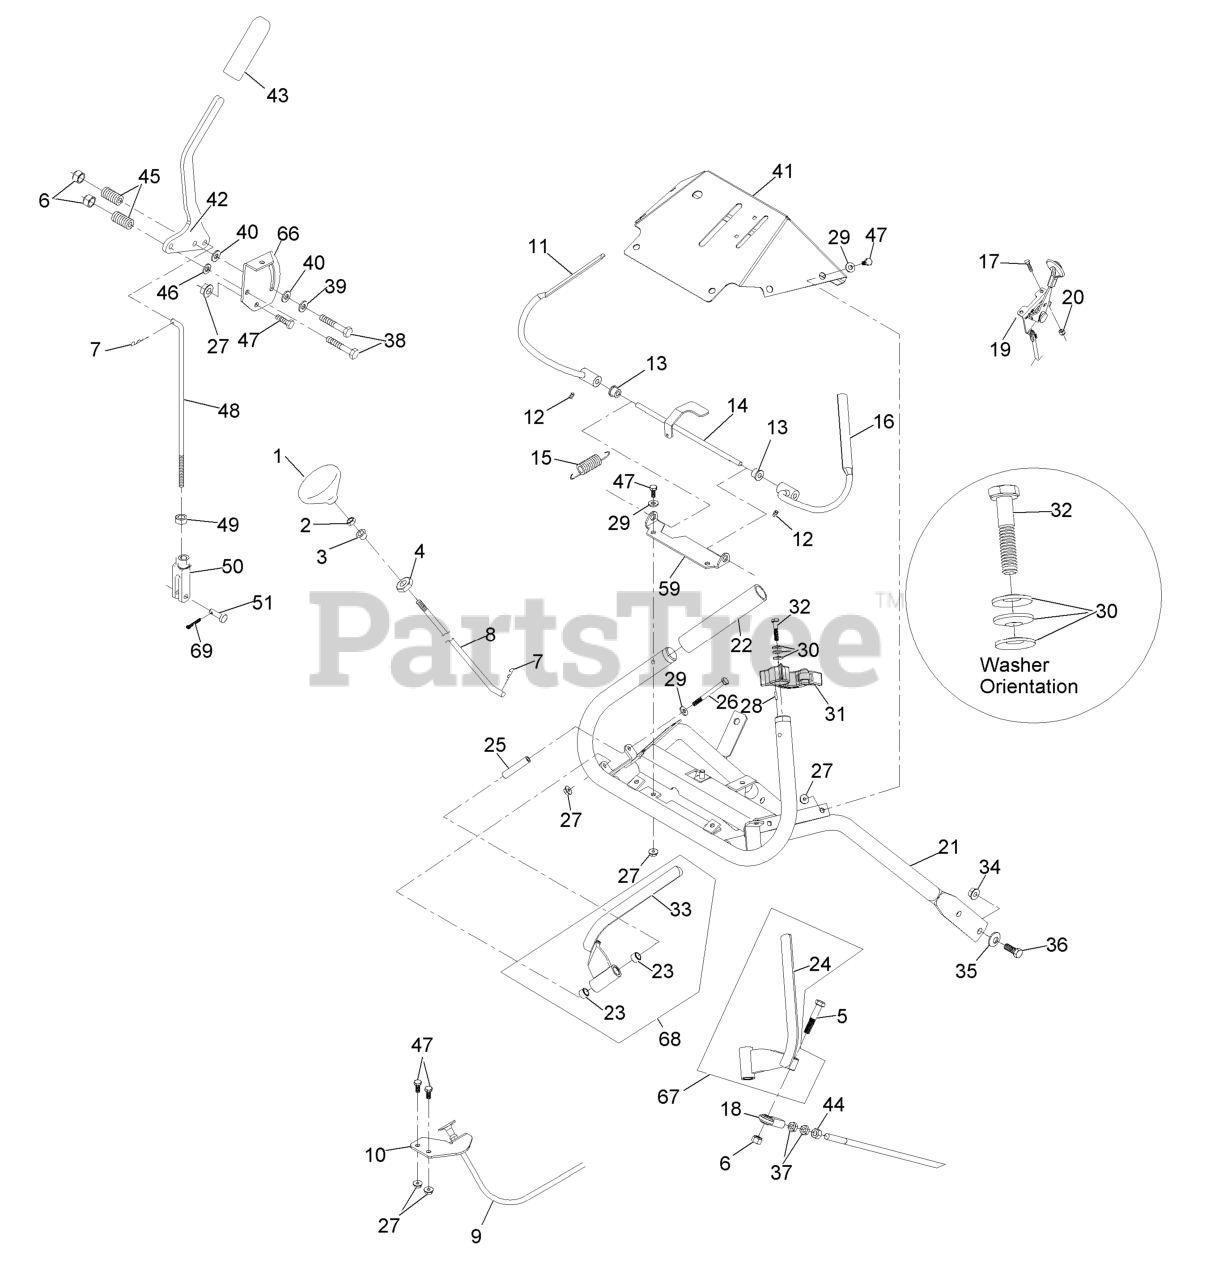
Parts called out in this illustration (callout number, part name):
1	KNOB-PUSH / PULL
2	NUT-JAM
3	BEARING-NYLON
4	NUT-PUSH
5	SCREW-HH
6	NUT-LOCK, NI
7	PIN-COTTER
8	LINKAGE,BLADE PUSH/PULL
9	CABLE-CHOKE
10	BRACKET-CABLE, CHOKE
12	SCREW-SET
13	BUSHING-NYLON
14	WLD,OPC LEVER AXLE
15	SPRING-EXTENSION
16	WLD,RH OPC LEVER
17	BOLT-CARR
18	JOINT-BALL, END
19	CONTROL, THROTTLE
20	NUT-LOCK, NI
21	WLD,VH ECS HANDLE
22	GRIP-BAR, HANDLE
23	BUSHING-SLEEVE
24	Lever, Drive Lh
25	BUSHING-LEVER, DRIVE
26	SCREW-HH
29	WASHER-FLAT
30	WASHER-SPRING
31	ASM,LATCH RH THUMB
31	ASM,LATCH LH THUMB
32	SCREW-HH
33	Lever, Drive Rh
34	NUT-HHF, WHIZ
35	WASHER-BELLEVILLE
36	SCREW-HH
37	NUT-HJ
38	SCREW-HH
39	WASHER-FRICTION
40	WASHER-FRICTION
41	ASM,CONSOLE W/DECALS
43	GRIP-HANDLE, STEERING
44	NUT-HEX
45	SPRING-COMPRESSION
46	WASHER-PLAIN
47	SCREW-HH
48	ROD-CONTROL, SPEED
49	NUT-JAM
50	YOKE-ADJUSTABLE
51	PIN-CLEVIS
59	BRACKET,OPC AXLE
66	BRACKET,SHIFTER SLIDE (PL
67	DRIVE LEVER-ASM, RH
68	DRIVE LEVER-ASM, LH
69	PIN-COTTER
